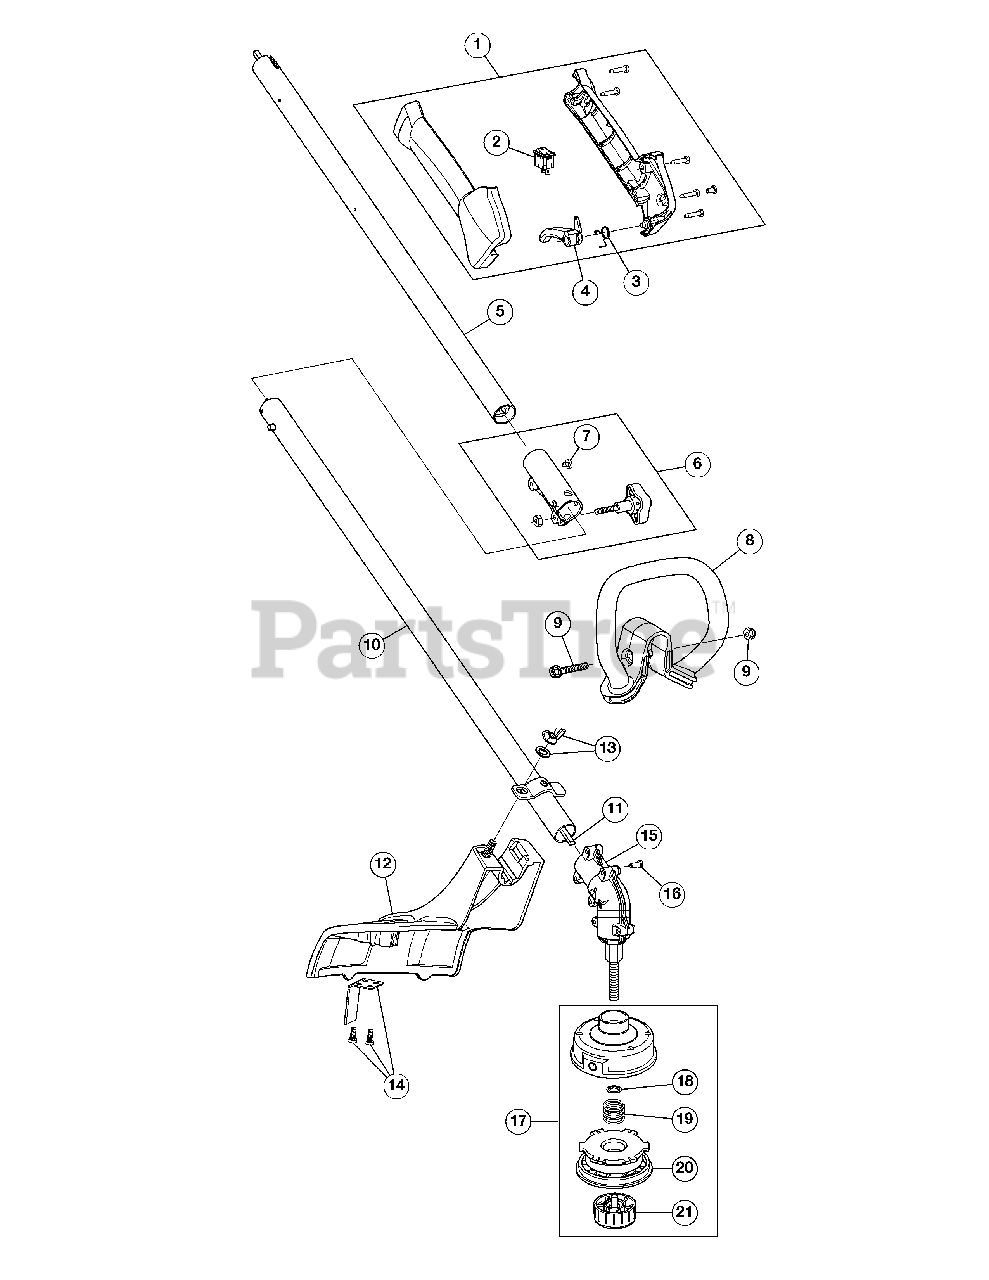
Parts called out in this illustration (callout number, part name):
1	Throttle Housing Assembly (Incl. 2 - 4)
2	Switch Assembly
3	Throttle Trigger Spring
4	Throttle Trigger
5	Upper Drive Shaft Housing Assembly
6	Split Boom Coupler (Incl. 7)
8	D-Handle (Incl. 9)
9	D-Handle Bolt
10	Lower Drive Shaft Housing Assembly
11	Lower Flexible Drive Shaft
12	Shield Assembly (Incl. 13 & 14)
13	Shield Mounting Hardware
14	Blade Assembly
15	Gear Box Assembly (Incl. 16 - 21)
16	Anti-Rotation Screw
17	Outer Spool Assembly
18	Retainer
20	Inner Reel
21	Bump Knob Assembly
